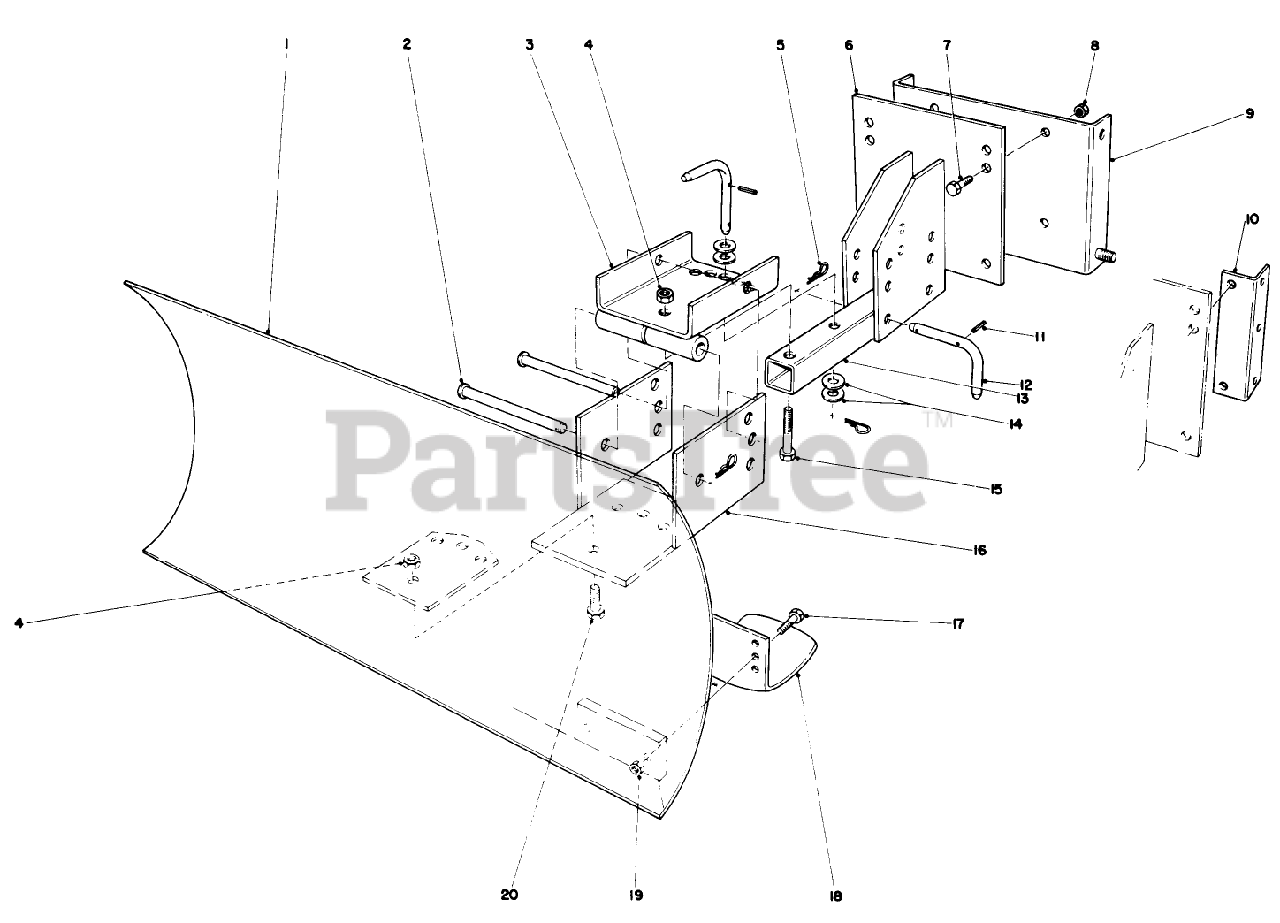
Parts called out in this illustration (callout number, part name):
1	Blade
2	PIN-CLEVIS
3	Swivel Bracket
4	1/2-13 CONELOCK NUT
5	PIN-HAIR
6	Mounting Plate
7	SCREW-HH
8	NUT-LOCK, CONE
9	Mounting Plate (Used with 826 & 1132 Units only)
10	Mounting Rail (used with 421 units only)
11	PIN-SPRING
12	Pivot Pin (Incl. Ref. #11)
13	Blade Tongue
14	WASHER-FLAT
15	SCREW-HH
16	Blade Adjustment
17	SCREW-HH
19	NUT-LOCK, CONE
20	SCREW-HH
